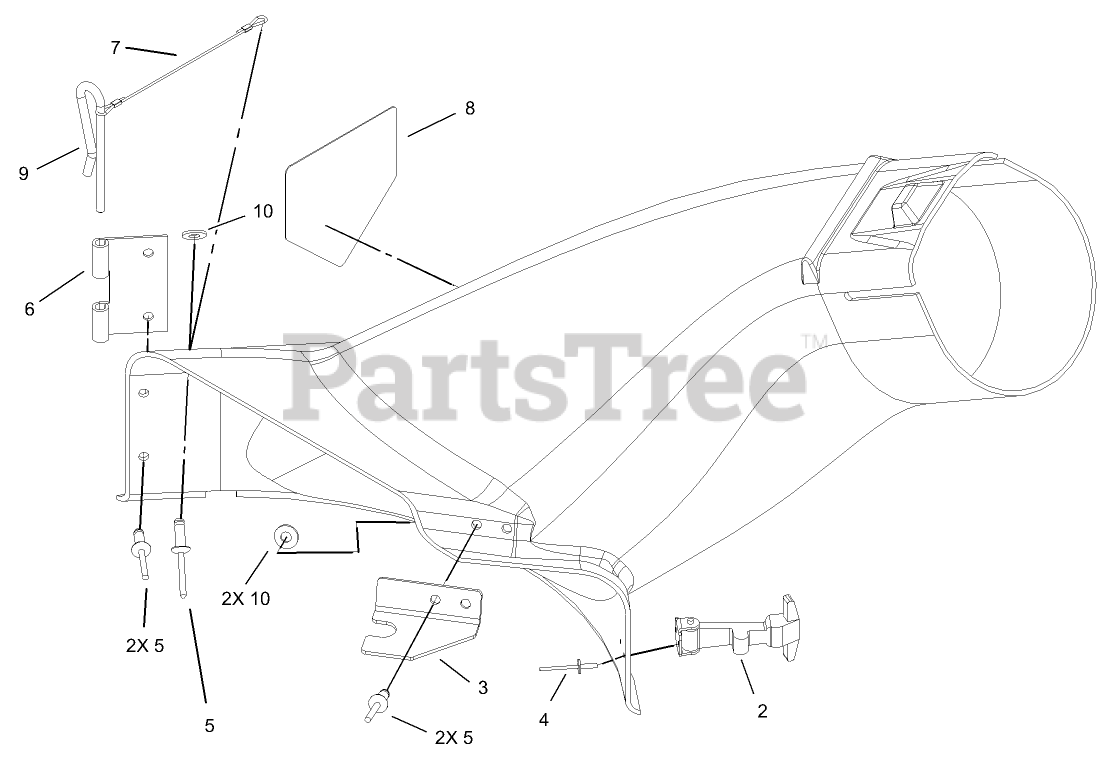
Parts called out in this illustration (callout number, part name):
2	HANDLE ASM
3	LATCH-ELBOW, BAGGER
4	RIVET-POP
5	RIVET-BLIND
6	BRACKET-MOUNTING, CHUTE
7	LANYARD
8	DECAL-DANGER
9	PIN-LOCKING, CHUTE
10	WASHER-FLAT
